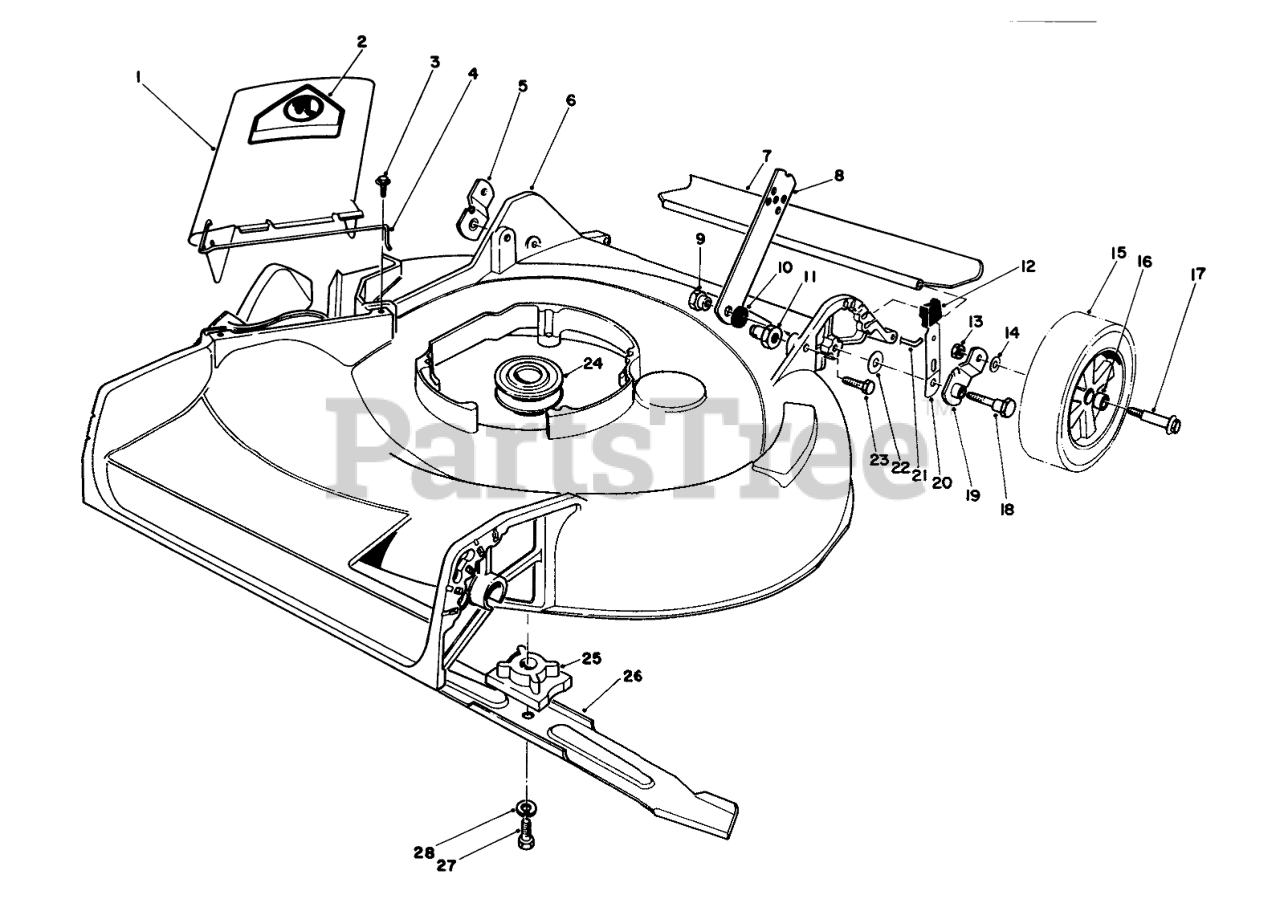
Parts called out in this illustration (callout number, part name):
1	Deflector Assembly (Incl. Ref. #2 & 4)
2	DECAL-DANGER
3	SCREW-HWH
4	SPRING HINGE
5	Pivot Arm
6	Housing-21"
7	Rear Shield
8	HANDLE LATCH
9	HANDLE PIVOT NUT
10	SPACER
11	HANDLE PIVOT NUT
12	KNOB-ARM
13	NUT-LOCK
13	Nut
14	WASHER
15	Wheel & Tire Assembly (Incl. Ref. #16)
16	BUSHING
17	WHEEL BOLT
17	BOLT-WHEEL
18	PIVOT SCREW
19	Pivot Arm
20	SPRING ARM ASM
21	SHIELD ROD
22	WASHER-PIVOT
23	SCREW-HH
24	PULLEY-DRIVER
25	BLADE RETAINER
26	Blade
27	SCREW-HH
28	WASHER-LOCK
